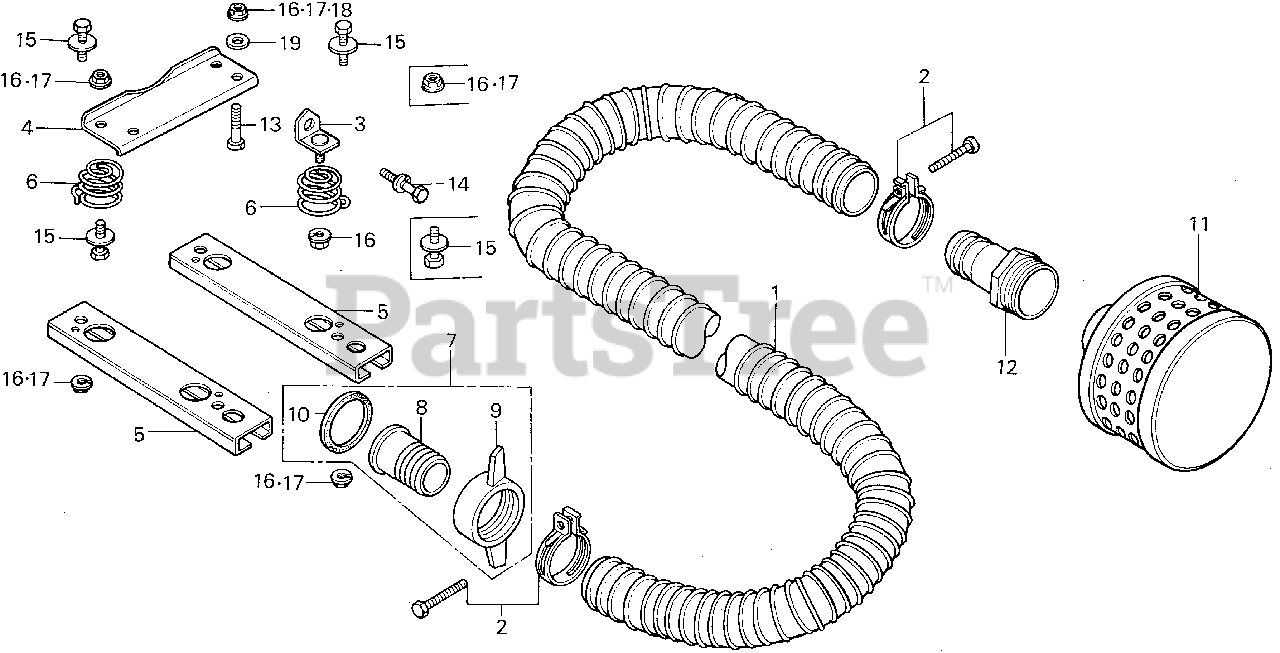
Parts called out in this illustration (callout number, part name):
1	HOSE, SUCTION (RUBBER)
1	HOSE, VINYL (2 INCHES)
2	BAND, HOSE (NOT AVAILABLE)
3	STAY, MOUNT
4	BRACKET, ENGINE
5	BED, FRAME
6	SPRING, MOUNT
7	COUPLING ASSY., HOSE (NOT AVAILABLE)
8	COUPLING, HOSE
9	RING, HOSE CLAMP
10	GASKET, COUPLING
12	JOINT, STRAINER
13	BOLT, HEX. (8X40) (NOT AVAILABLE)
14	BOLT-WASHER (8X40)
15	BOLT-WASHER (8X20)
16	NUT, FLANGE (8MM)
17	NUT-WASHER (8MM)
19	WASHER, PLAIN (8MM)
